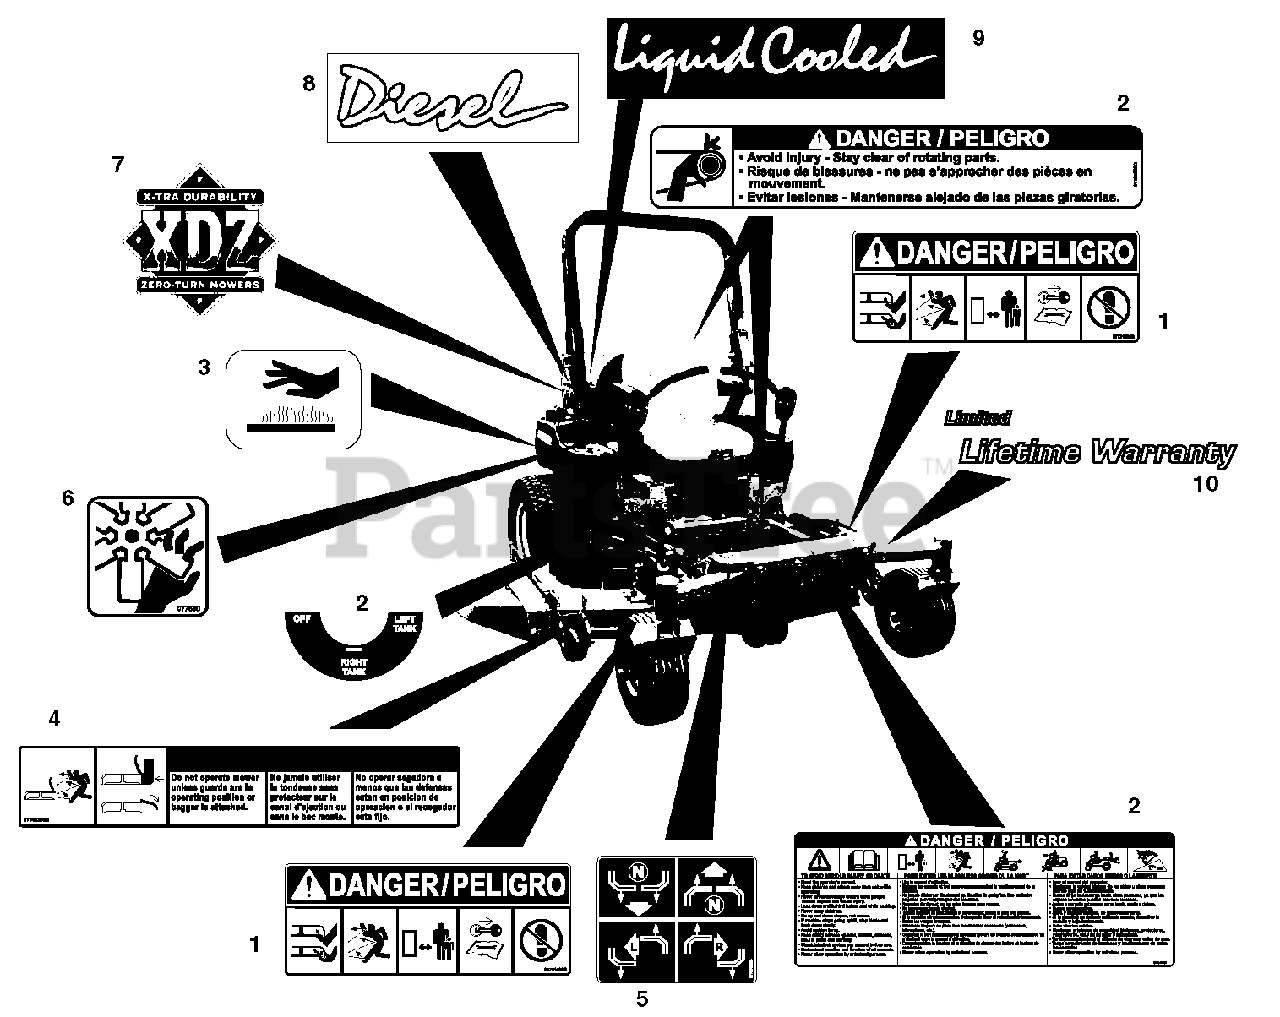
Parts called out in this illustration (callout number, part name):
1	Decal, Mower Pan Head Danger
2	Set, Decal - Common Danger/Fuel
3	Decal, Hot Surface
4	Decal, Warning
5	Decal, Instructional
6	Decal, Danger Fan
7	Decal, XDZ
8	Decal, Diesel (195)
8	Decal, Turbo Diesel (196)
9	Decal, Liquid Cooled
10	Decal, Limited Lifetime Warranty
